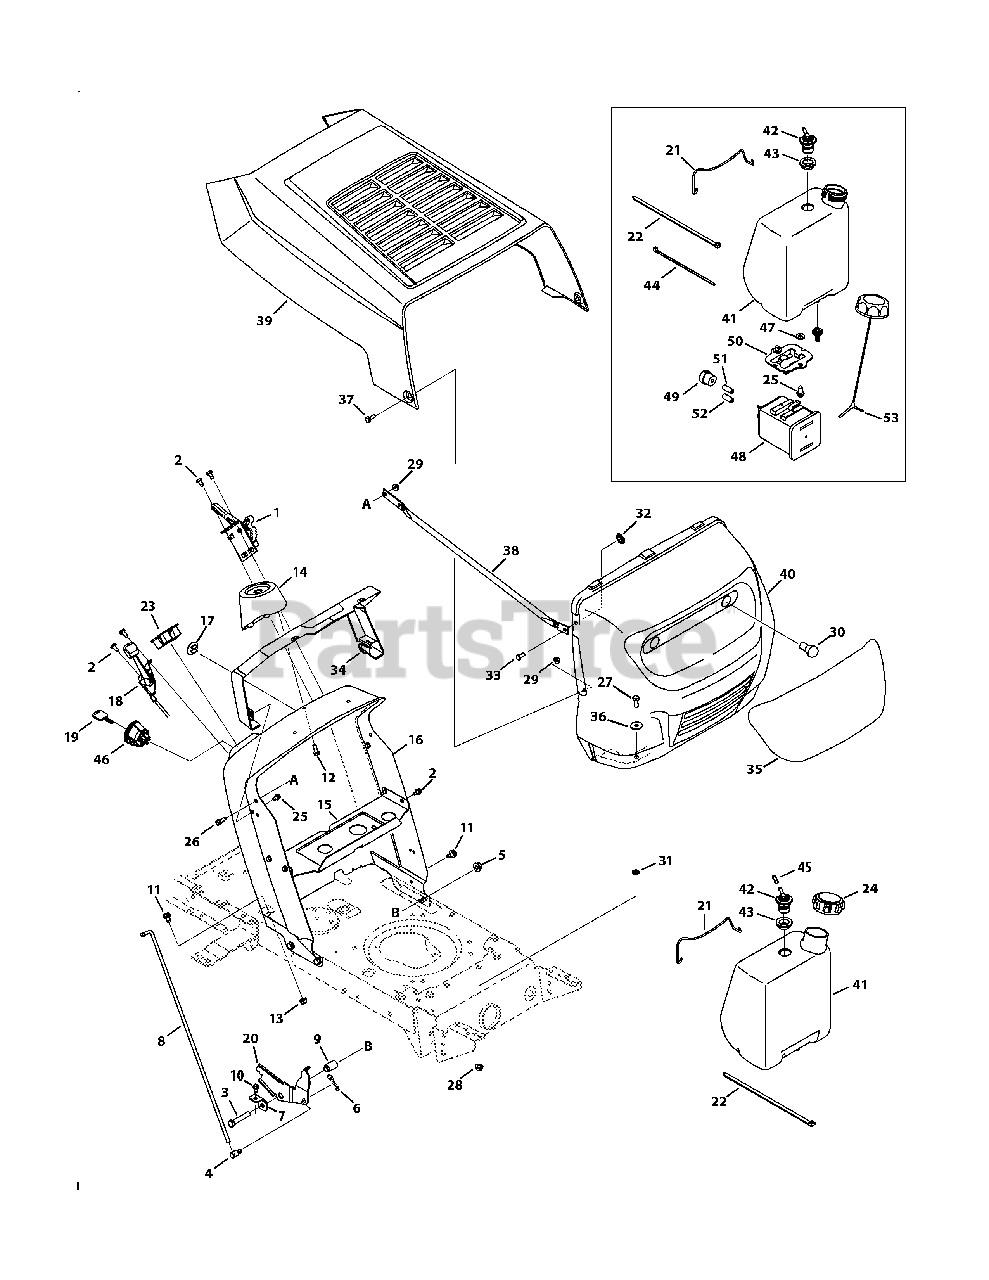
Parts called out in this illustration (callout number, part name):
1	7-Speed Control Assembly
1	6-Speed Control Assembly
2	Screw, 1/4-20 x .500
3	Hex Screw, 3/8-16 x 2.0
4	Ferrule, 1/4-20 x 1.00
5	Flangelock Nut, 3/8-16
6	Bow Tie Cotter Pin, 72
7	Speed Latch Tab
8	Speed Selector
9	Flange Spacer, .390 x .671 x 1.095
10	Hex Washer Screw, 1/4-20 x .500
11	Screw, 5/16-18 x .625
12	Screw, 1/4 x .750
13	Flangelock Nut, 5/16-18
14	Steering Support
15	Gas Tank Support Bracket
16	Dash, No RMC
17	Choke Plug
18	Throttle/Choke Cable
20	Speed Latch. RMC
20	Speed Latch, No RMC
21	Battery Assembly Rod
22	Cable Tie
23	Ammeter
24	Fuel Cap
24	Fuel Cap W/ Tether
25	Screw, 5/16-18 x .750
26	Screw, 1/4-20 x .750
27	Hex Screw, 5/16-18 x .75
28	Flangelock Nut, 5/16-18
29	Flangelock Nut, 1/4-20
30	Miniature Lamp 12V Socket
31	Speed Nut, .3125
32	Push-On Nut, .25
33	Flat Head Rivet, 1/4"
36	Flat Washer, .344 x 1.0 x .063
37	Shoulder Bolt, 1/4-20 x .375 x .125
38	Grill Support Rod
39	Hood - Red
39	Hood - Gray
39	Hood - Green
40	Grille - Red
40	Grille - Gray
40	Grille - Green
41	1.5 Gallon Fuel Tank
41	1.36 Gallon Fuel Tank
42	Rollover Valve
43	Rubber Grommet, 23 x 3.55
44	Cable Tie
45	Hose Vent, 3/16
46	Key Switch
47	Flat Washer, .344 x .750 x .120
48	5 Gallon Carbon Canister
49	Vent Filter Canister
50	Canister Adaptor Bracket
51	Hose, Fuel, Low Perm., White
52	Hose, Fuel, Low Perm., Yellow
53	Fuel Cap, 2.25"
